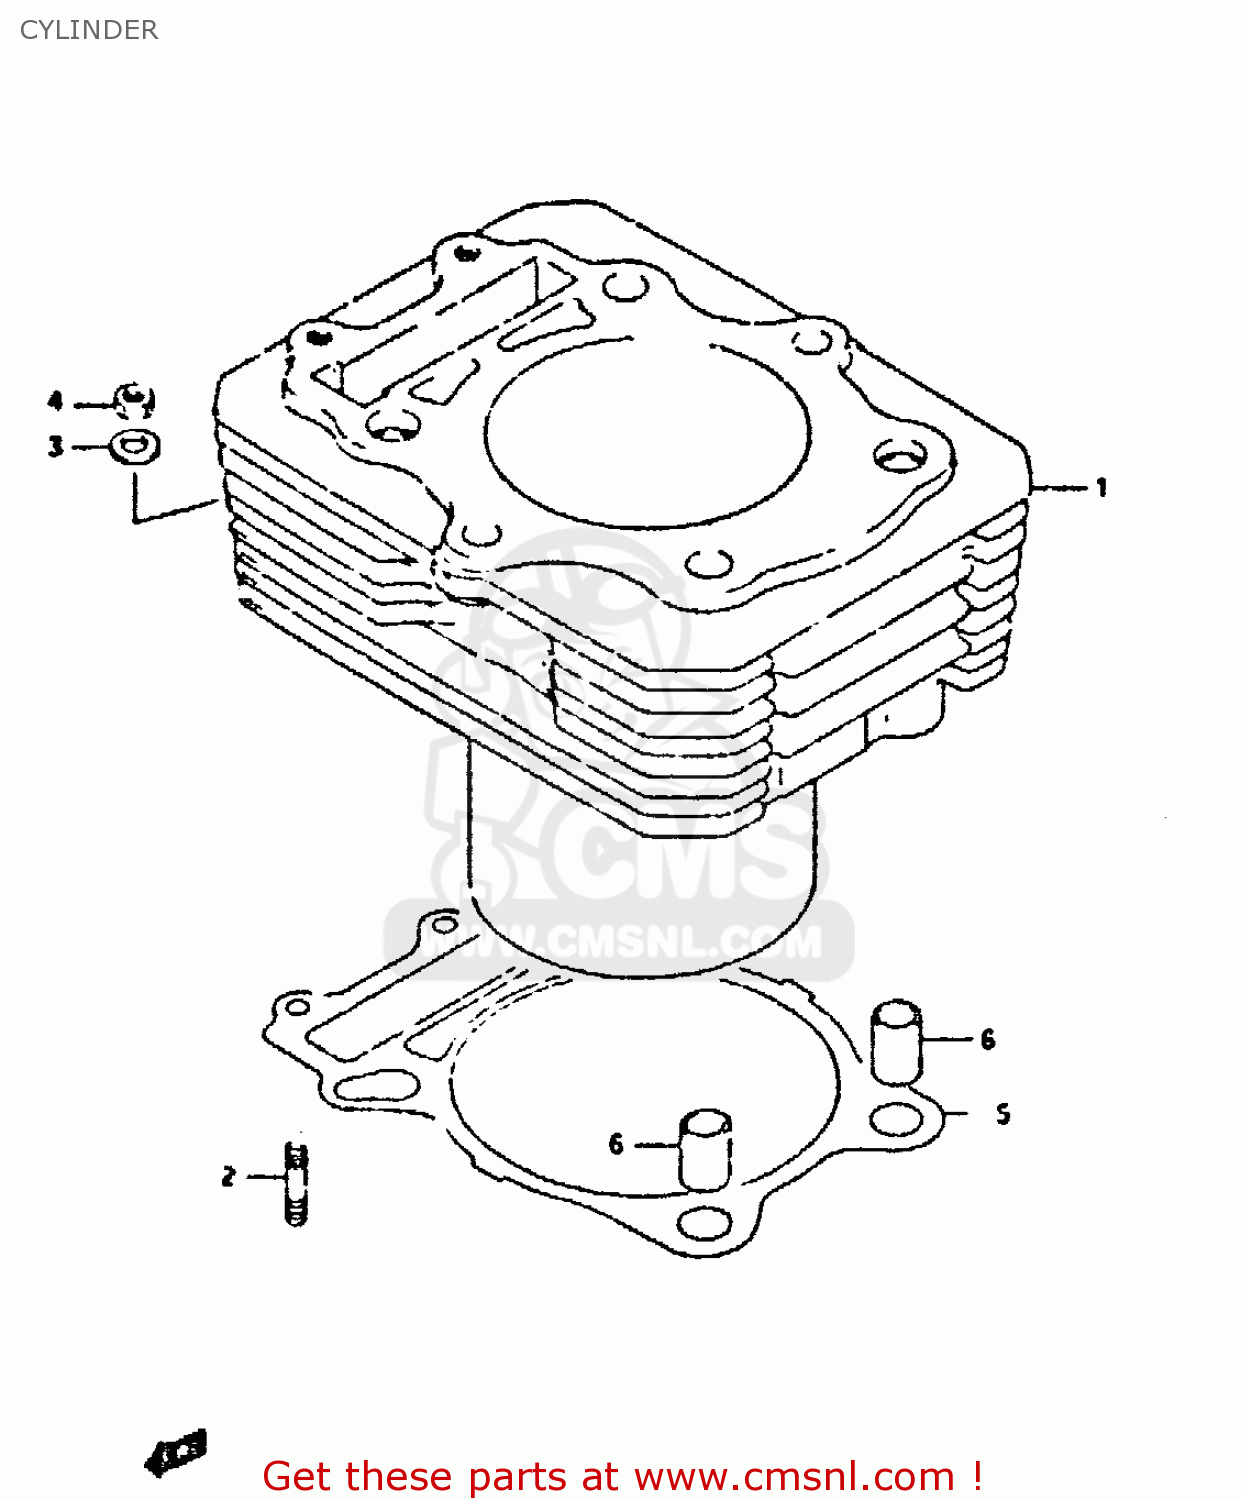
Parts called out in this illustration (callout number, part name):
1	CYLINDER
2	STUD 6X20
3	WASHER
4	NUT
5	GASKET,CYLINDER (NAS)
6	PIN
